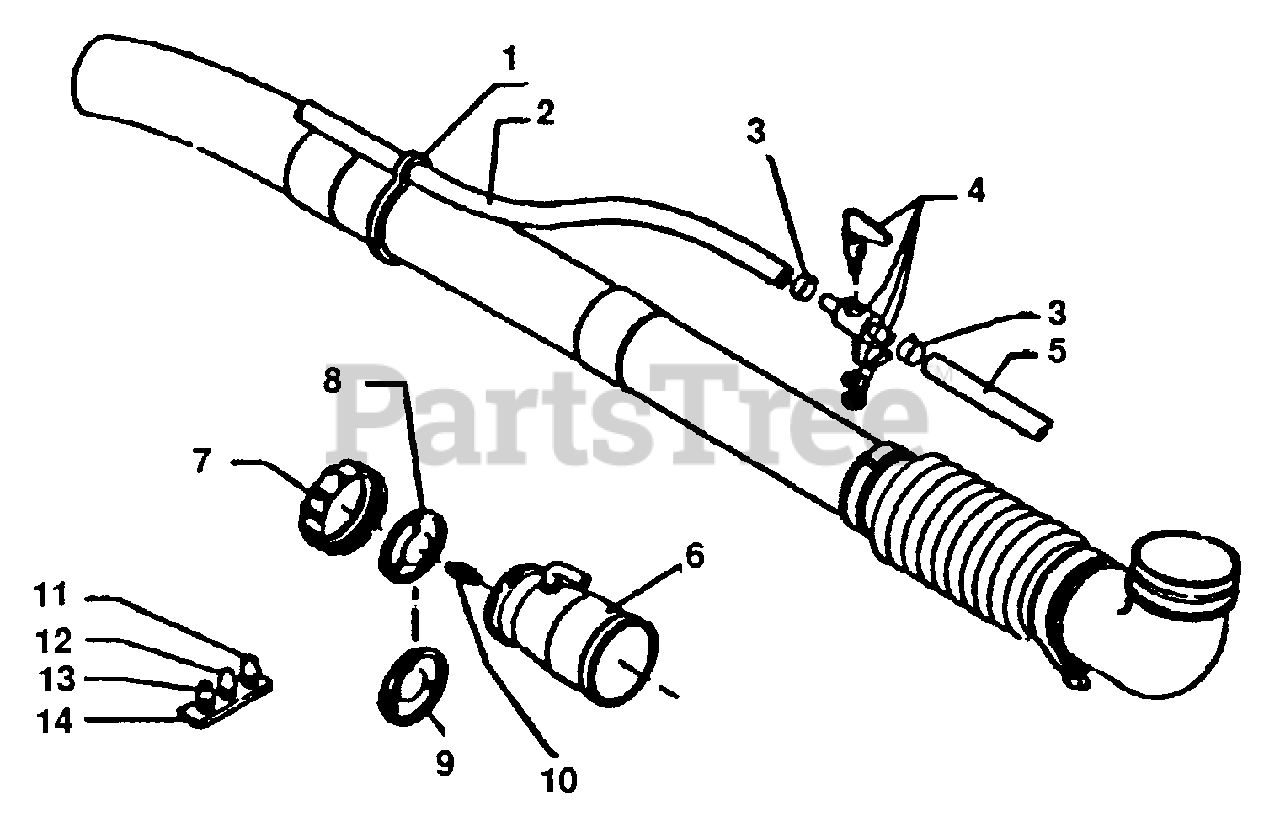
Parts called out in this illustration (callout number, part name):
1	CLIP
2	HOSE, FLUID
3	CLAMP
4	VALVE ASSY
5	HOSE, FLUID
6	NOZZLE - MISTING
8	DISC, ATOMIZER - S
9	DISC, ATOMIZER - F
10	NOZZLE - MISTING
11	NOZZLE - MISTING
12	NOZZLE - MISTING
13	NOZZLE - MISTING
14	HOLDER, NOZZLE
